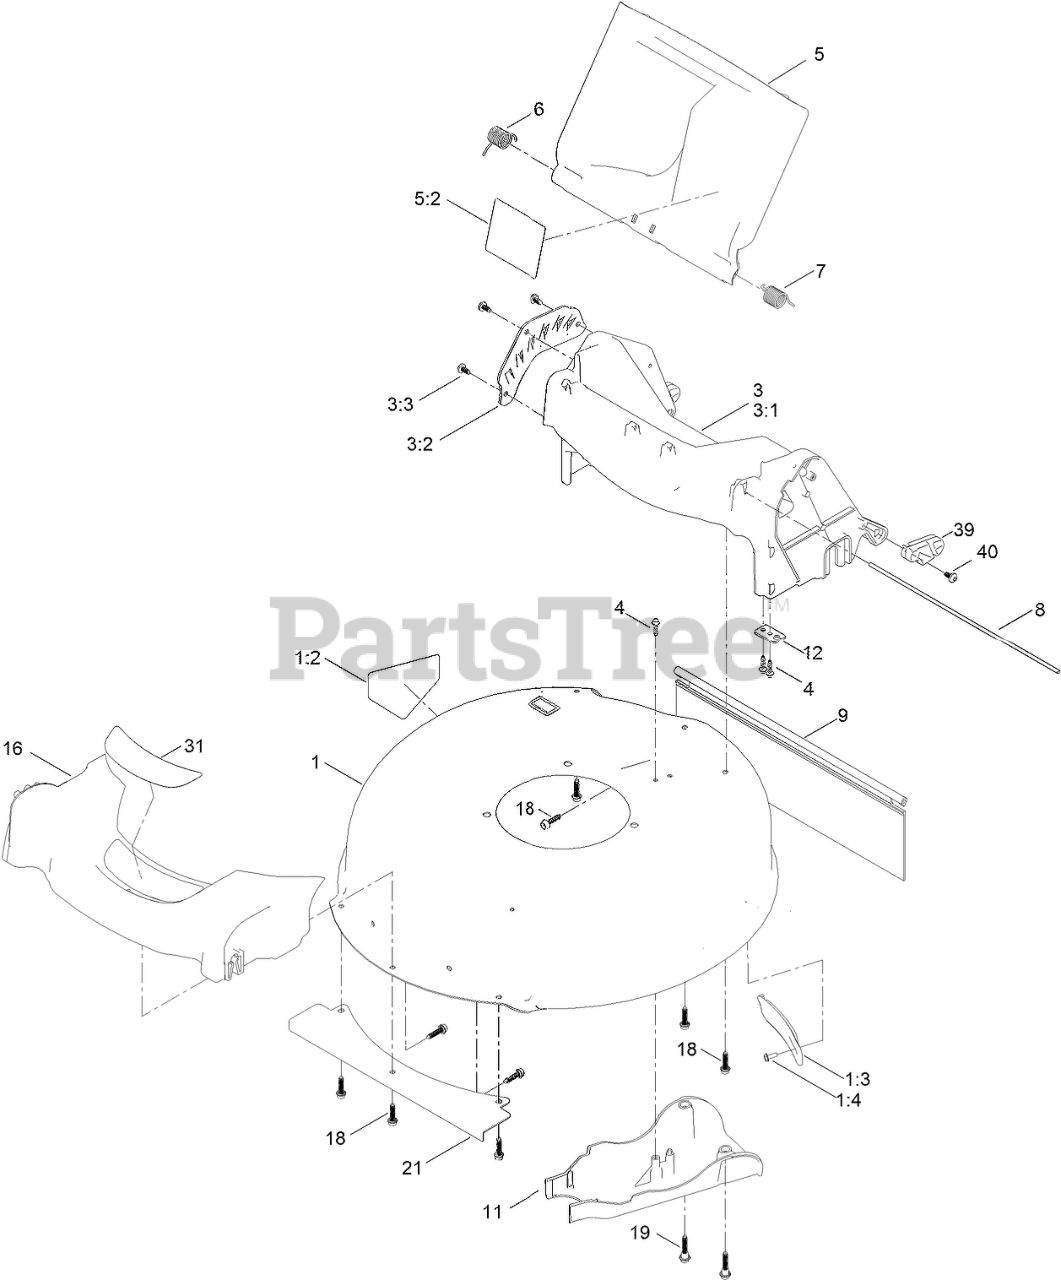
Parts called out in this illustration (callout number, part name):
1	HOUSING ASM
1:2	DECAL-DANGER
1:3	COVER-BELT
1:4	SCREW-TAPTITE
3	CHUTE ASM
3:1	CHUTE-SP/AWD, 21 IN
3:2	PLATE-HOC
3:3	SCREW-PLASTIC,PH
4	SCREW-PLASTIC, HWH
5	REAR DEFLECTOR ASM (60V)
5:2	DECAL-WPM WARNING, 60V
6	SPRING-TORSION
7	SPRING-TORSION
8	ROD-DOOR
9	SHIELD-TRAILING
11	COVER-BELT
12	BRACKET-CABLE
16	BUMPER
18	SCREW-FLANGE, PLASTIC
19	SCREW-SHOULDER, HHF
21	SHIELD-FRONT
31	DECAL-DECK
39	PAD-STOW, SMART
40	SCREW-PLASTIC,PH
